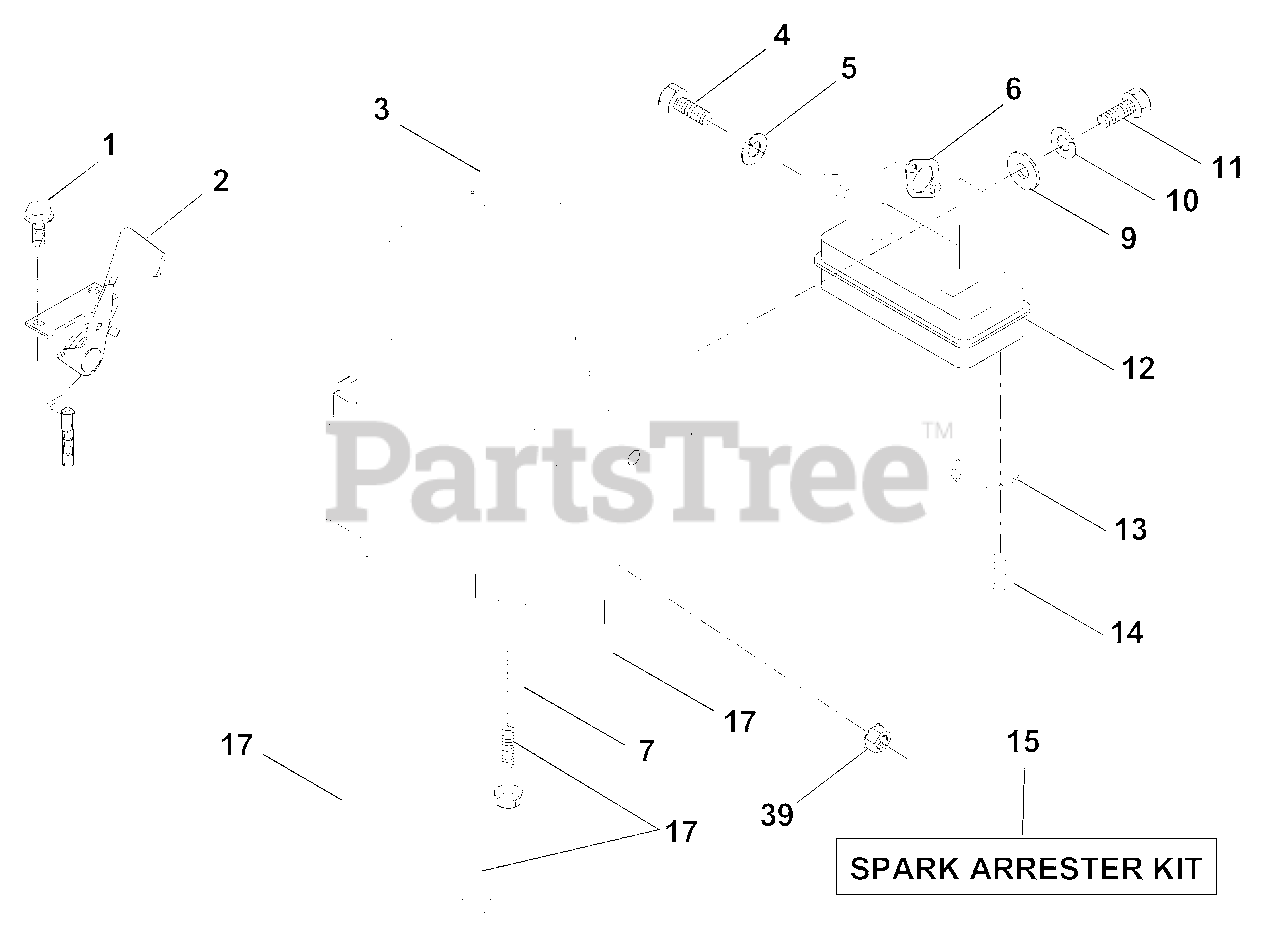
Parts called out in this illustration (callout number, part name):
1	Screw, Hex Thd. Cut 1/4-20 x 1/2
2	Control, Throttle
3	Engine, Briggs and Stratton Model No. 283707
4	Screw, Hex, Cap 5/16-18 x 3/4
5	Washer, Lock Heavy Helical Spring 5/16
6	Gasket, Exhaust
7	Washer, Lock Ext. Tooth 3/8
9	Washer 5/16 x 3/4 x 16
10	Washer, Lock Hvy Hlcl Spring 1/4
11	Bolt, Hex Fin.
13	Deflector, Muffler
14	Screw, Spiderloc Hex Hd #8 x 1/2 AB
15	Arrester, Spark
17	Screw, Hex Washer Head, Thdrol. 3/8-16 x 1-1/2
39	Nut, Flange 1/4-20
